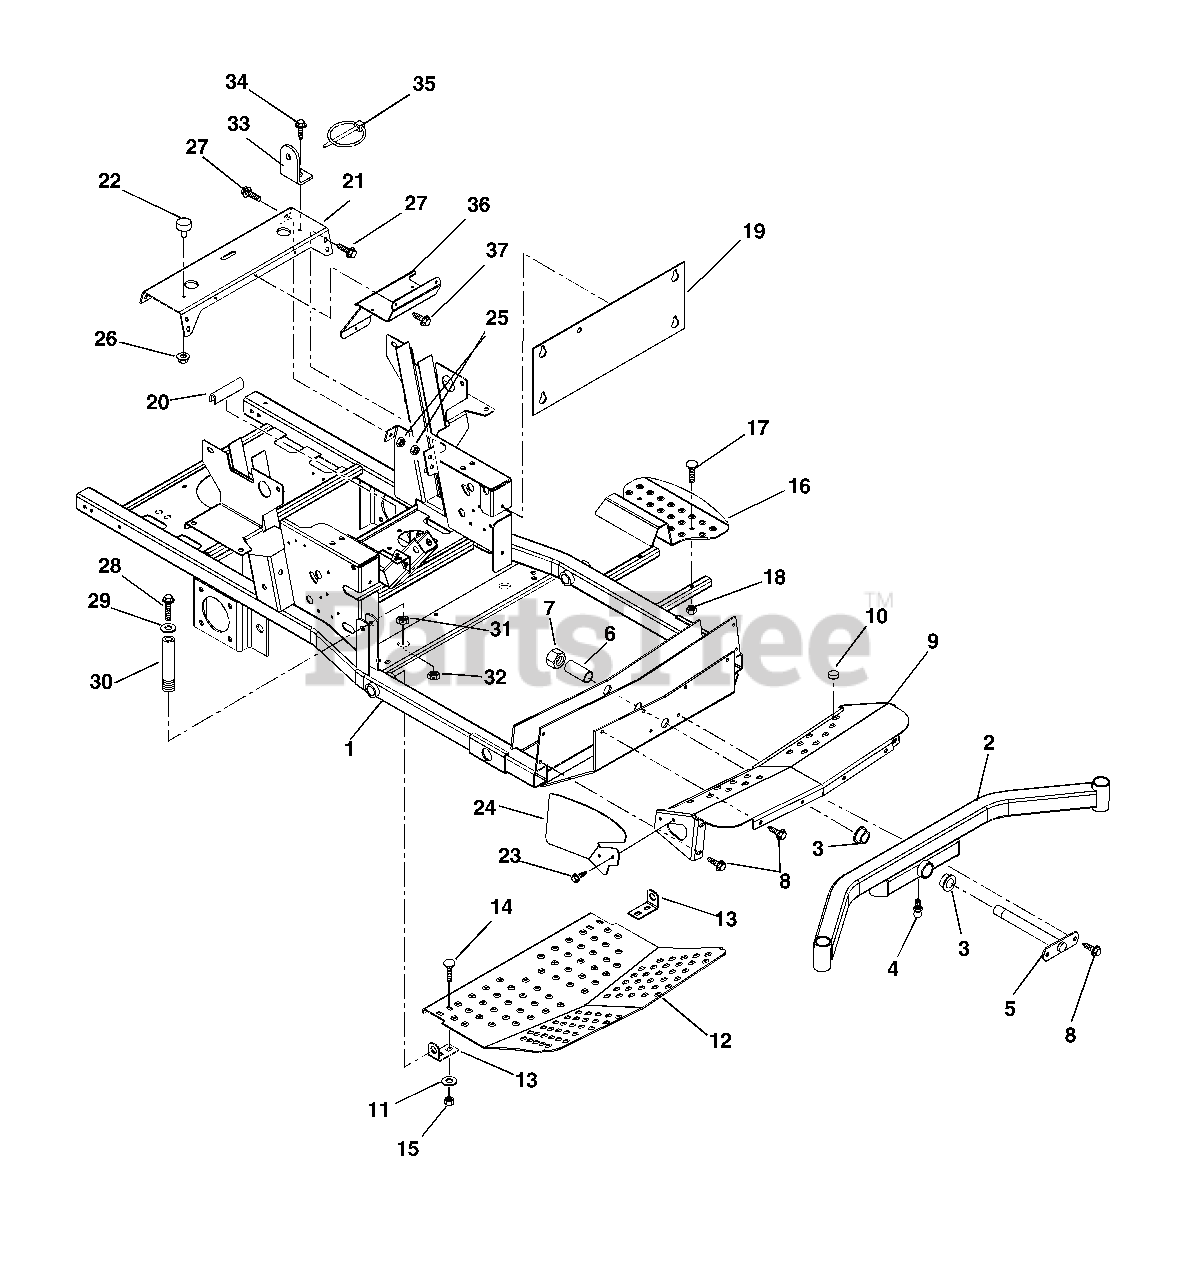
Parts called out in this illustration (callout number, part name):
2	Axle-Front
3	Bushing-Flange 1.020 x 1.385 x .75 x 1.75
4	Fitting-Lube .25-28 x .256
5	Pin-Axle
7	Nut-Locking-Nylon 1.0-14
8	Screw-Tapping .38-16 x .75
9	Cover-Axle
10	Button Bumper
11	Washer-Flat-Steel .38 x .875 x .083
12	Panel-Inspection
13	Mount-Inspection Panel
14	Bolt-Round Head Square Neck .38-16 x 1.00 Grade 5
15	Nut-Locking-Nylon .38-16
16	Step-Ingress
17	Bolt-Round Head Square Neck .31-18 x 1.50 Grade 5
18	Nut-Locking-Center .31-18
19	Plate-Kick
20	Strip -Cowl
21	Channel-Cross
22	Bumper, Rubber
23	Screw-Tapping .25-20 x .50 Hex Washer Head
24	Cover, Cylinder Rod End
25	Nut-Retainer .375-16 x .37
26	Nut-Locking-Flange .312-24
27	Bolt-Serrated Flange Washer Head .38-16 x 1.00
28	Bolt-Hex .50-20 x 1.00 Grade 5
29	Washer-Flat-Steel .531 x 1.06 x .095
30	Post
31	Nut-Jam .75-16
32	Nut, Jam Center-Lock .75-16
33	Bracket, Seat Lock
34	Screw-Tapping .25-20 x .50 Hex Washer Head
35	Pin-LOK .31 x 2.00
36	Bracket, EFI Pump and Regulator
37	Screw-Tapping .25-20 x .50 Hex Washer Head
